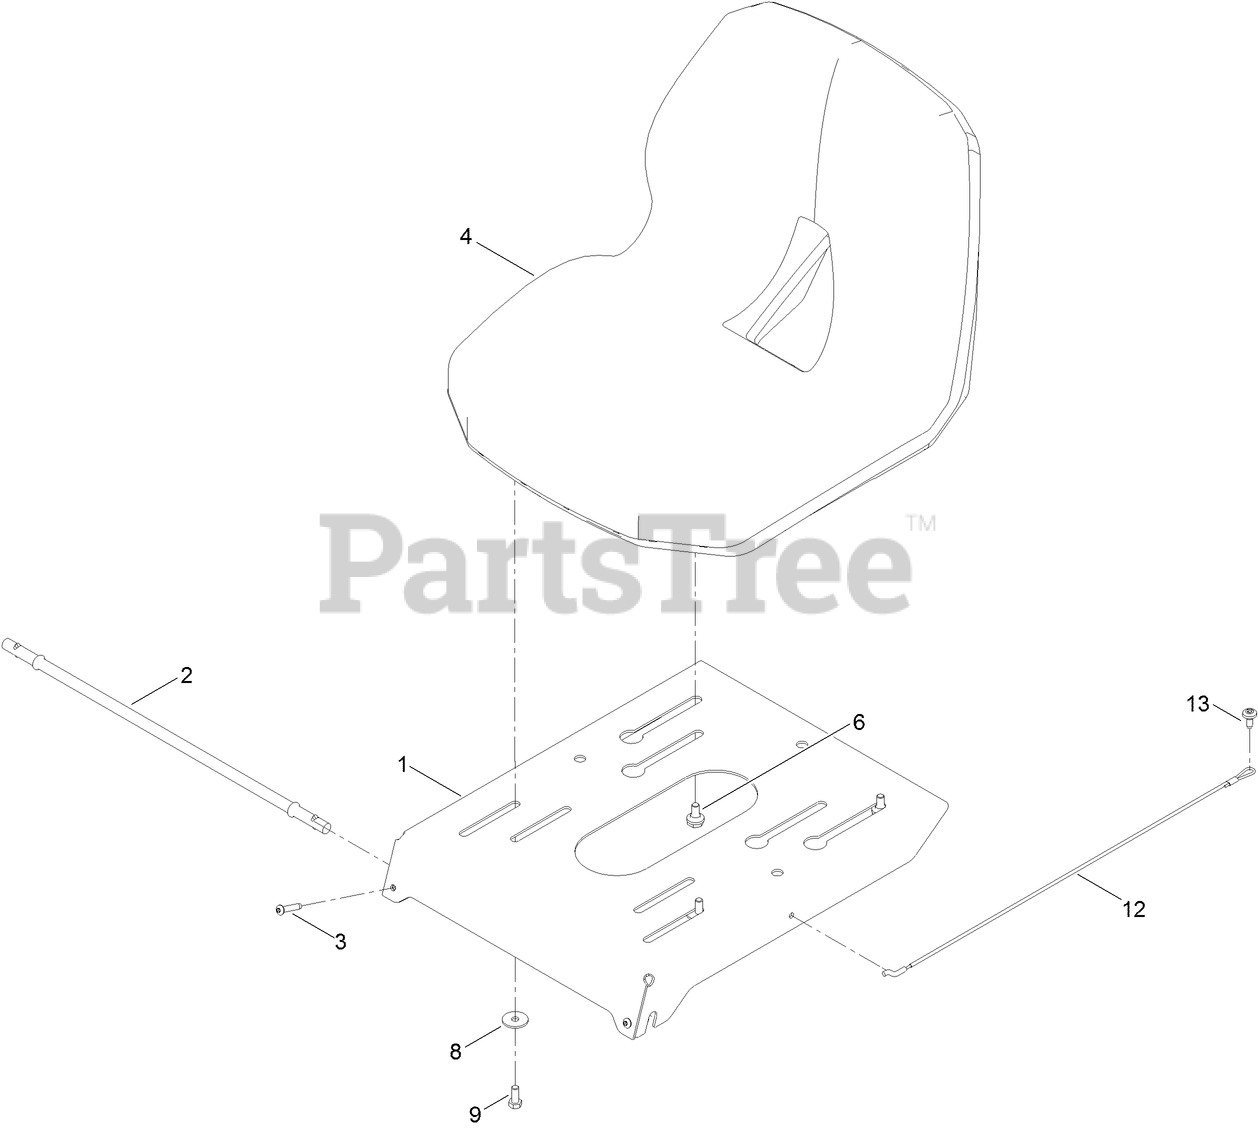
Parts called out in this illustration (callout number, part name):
1	PAN-SEAT
2	ROD-PIVOT
3	SCREW-BHCS
4	SEAT-16 IN
6	BOLT-SHOULDER,HFH
8	WASHER-PIVOT
9	SCREW-HH
12	CABLE-LANYARD
13	SCREW-SHOULDER
